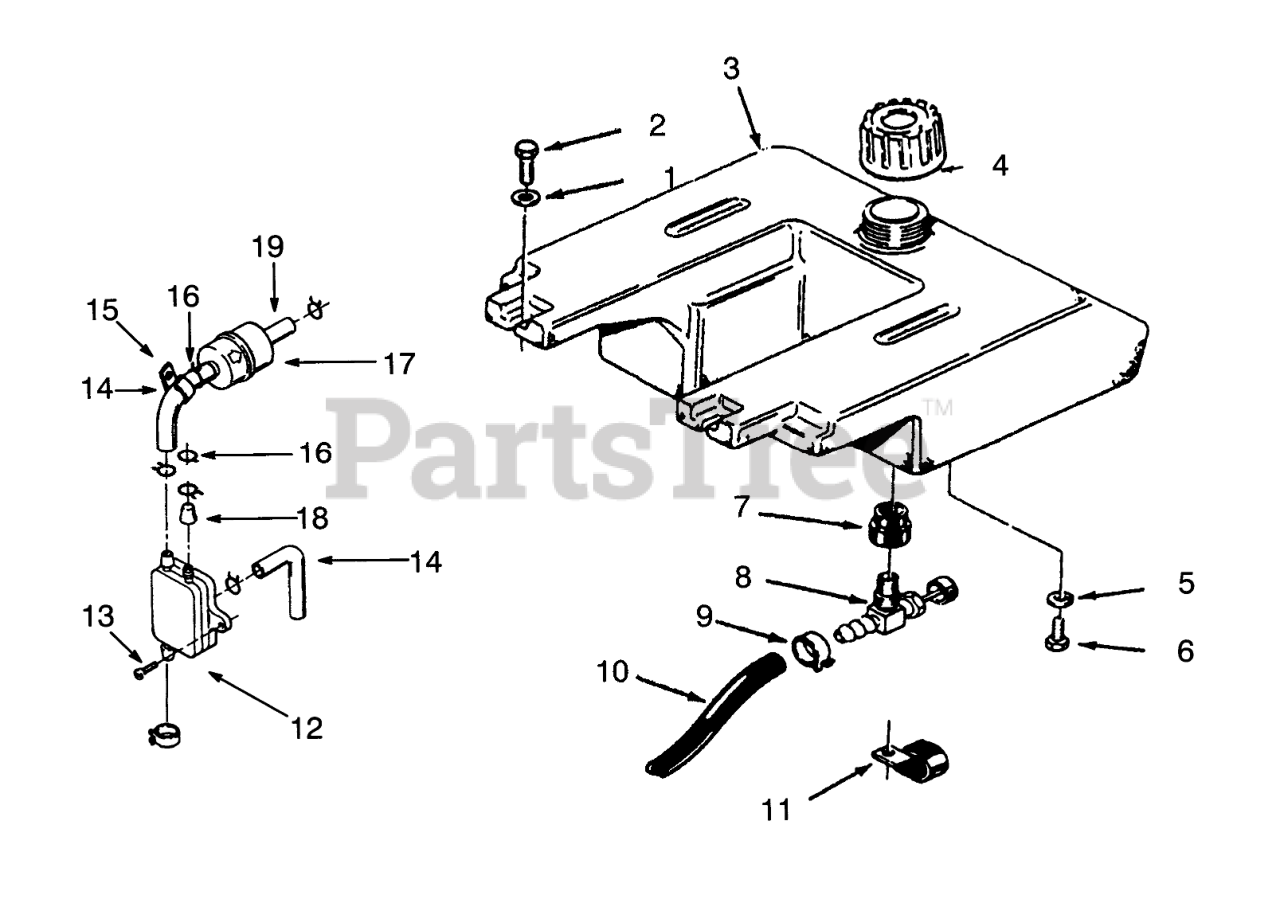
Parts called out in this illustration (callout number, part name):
1	WASHER-FLAT
2	Bolt
3	Tank-Fuel(Incl. Ref. #5 & 7)
4	GAS CAP ASM
5	WASHER-LOCK
6	SCREW-HH
7	BUSHING
8	VALVE-FUEL
9	Clamp
10	Fuel Line 62
11	Clamp
12	PUMP-FUEL
13	SCREW-TAPPING PAN HD
14	Hose
15	Clip
16	CLAMP-HOSE
17	Filter-Fuel
18	CAP-FUEL OUTLET
19	FUEL HOSE
